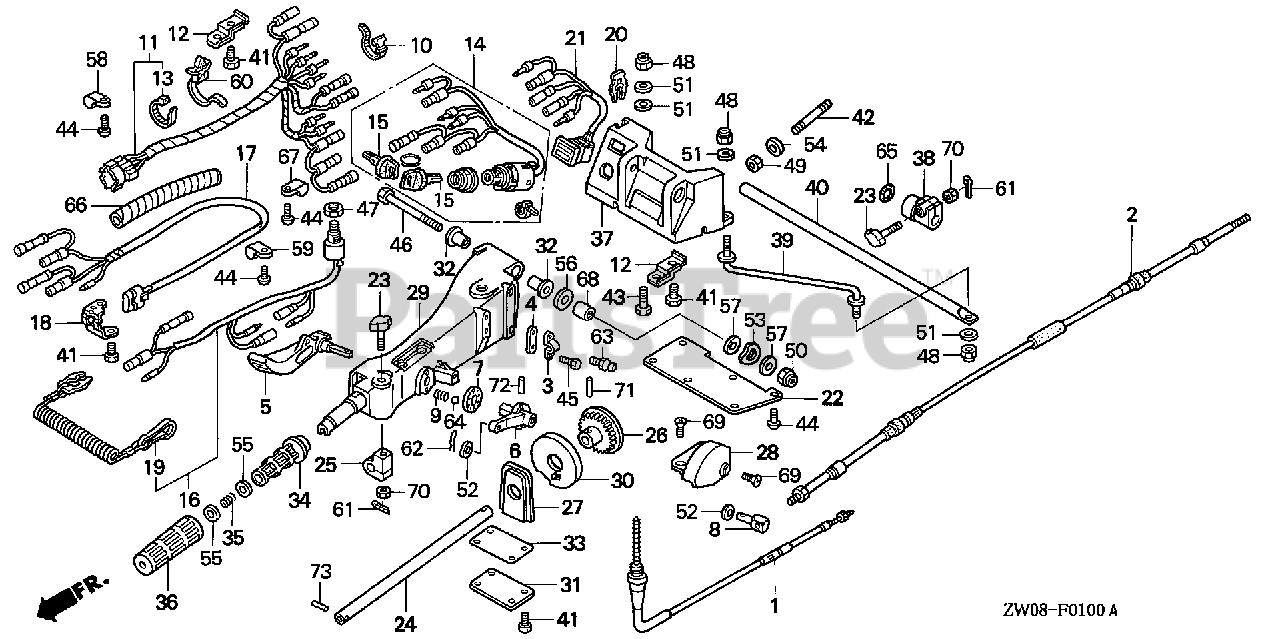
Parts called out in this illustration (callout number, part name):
1	CABLE, THROTTLE
2	CABLE, SHIFT
3	HOLDER, SHIFT CABLE
4	PLATE, SHIFT CABLE
5	LEVER, SHIFT
6	LINK, SHIFT (A)
7	PLATE, CLICK BASE
8	PIVOT, SHIFT
9	SPRING, CLICK
10	BAND B1, CABLE Use up to Frame SN 1001879.
11	HARNESS ASSY., CONTROL PANEL
12	STAY C, ENGINE WIRE HARNESS
13	TIE, CABLE (NATURAL 2.4X92) Use up to Frame SN 1300359.
14	SWITCH ASSY., COMBINATION
15	KEY ASSY., COMBINATION SWITCH (35100-ZV5-003 ONLY) DUAL QTY = (4) (SINGLE)
16	SW, EMERGENCY STOP
17	SWITCH ASSY., POWER TRIM-TILT
18	STAY, POWER TILT SWITCH
19	WIRE, EMERGENCY (SINGLE) (DUAL)
20	CLIP, EMERGENCY LOCK
21	LAMP ASSY., INDICATION (2-LED) DUAL QTY = (2) (SINGLE)
22	COVER, STEERING BRACKET
23	BOLT, FRICTION
24	PIPE, THROTTLE
25	BLOCK, THROTTLE FRICTION
26	GEAR, THROTTLE REEL
27	BRACKET, THROTTLE REEL (A)
28	COVER, SHIFT LINK
29	HANDLEBAR *NH282MU* (OYSTER SILVER METALLIC-U)
30	CAP, CABLE HOLDER
31	PLATE, REEL SETTING
32	BUSH, HANDLEBAR
33	GASKET, REEL GEAR
34	PIPE, GRIP
35	SPRING, GRIP PIPE
36	RUBBER, GRIP
37	BRACKET, STEERING *NH282MU* (OYSTER SILVER METALLIC-U)
38	BLOCK, STEERING FRICTION
39	ROD, STEERING FRICTION
40	SHAFT, STEERING FRICTION
41	BOLT, HEX. (6X12) Use up to Frame SN 1005248.
42	BOLT, STUD (10X28)
43	BOLT, HEX. (8X32)
44	SCREW, PAN (5X12)
45	BOLT, HEX. (6X16)
46	BOLT, HEX. (12X100)
47	NUT, HEX. (16MM) DUAL QTY = (2) (SINGLE)
48	NUT, SELF-LOCK (8MM)
49	NUT, SELF-LOCK (10MM)
50	NUT, SELF-LOCK (12MM)
51	WASHER, PLAIN (8MM)
52	WASHER, PLAIN (6MM) Use from Frame SN 4800713.
53	WASHER, WAVE (14MM)
54	WASHER (10MM)
55	WASHER (10MM)
56	WASHER, PLAIN (12MM)
57	WASHER, PLAIN (12MM)
58	CLIP (10.7MM)
59	CLIP (7.5MM)
60	STRAP, CABLE (105MM) *NH1* (Honda Code 1685536). (BLACK)
61	PIN, SPLIT (2.0)
62	PIN, SPECIAL LOCK (6MM)
63	NIPPLE, GREASE
64	BALL, CLICK
65	O-RING (15.54X2.26)
66	TUBE, SPIRAL (9X110)
67	CLIP, WIRE HARNESS (6.3MM)
68	COLLAR, DISTANCE (12.2X22X21.5)
69	SCREW, OVAL (6X16)
70	NUT, HEX. (6MM)
71	PIN, SPRING (3X20)
72	PIN, SPRING (4X20)
73	PIN, SPRING (4X28)
